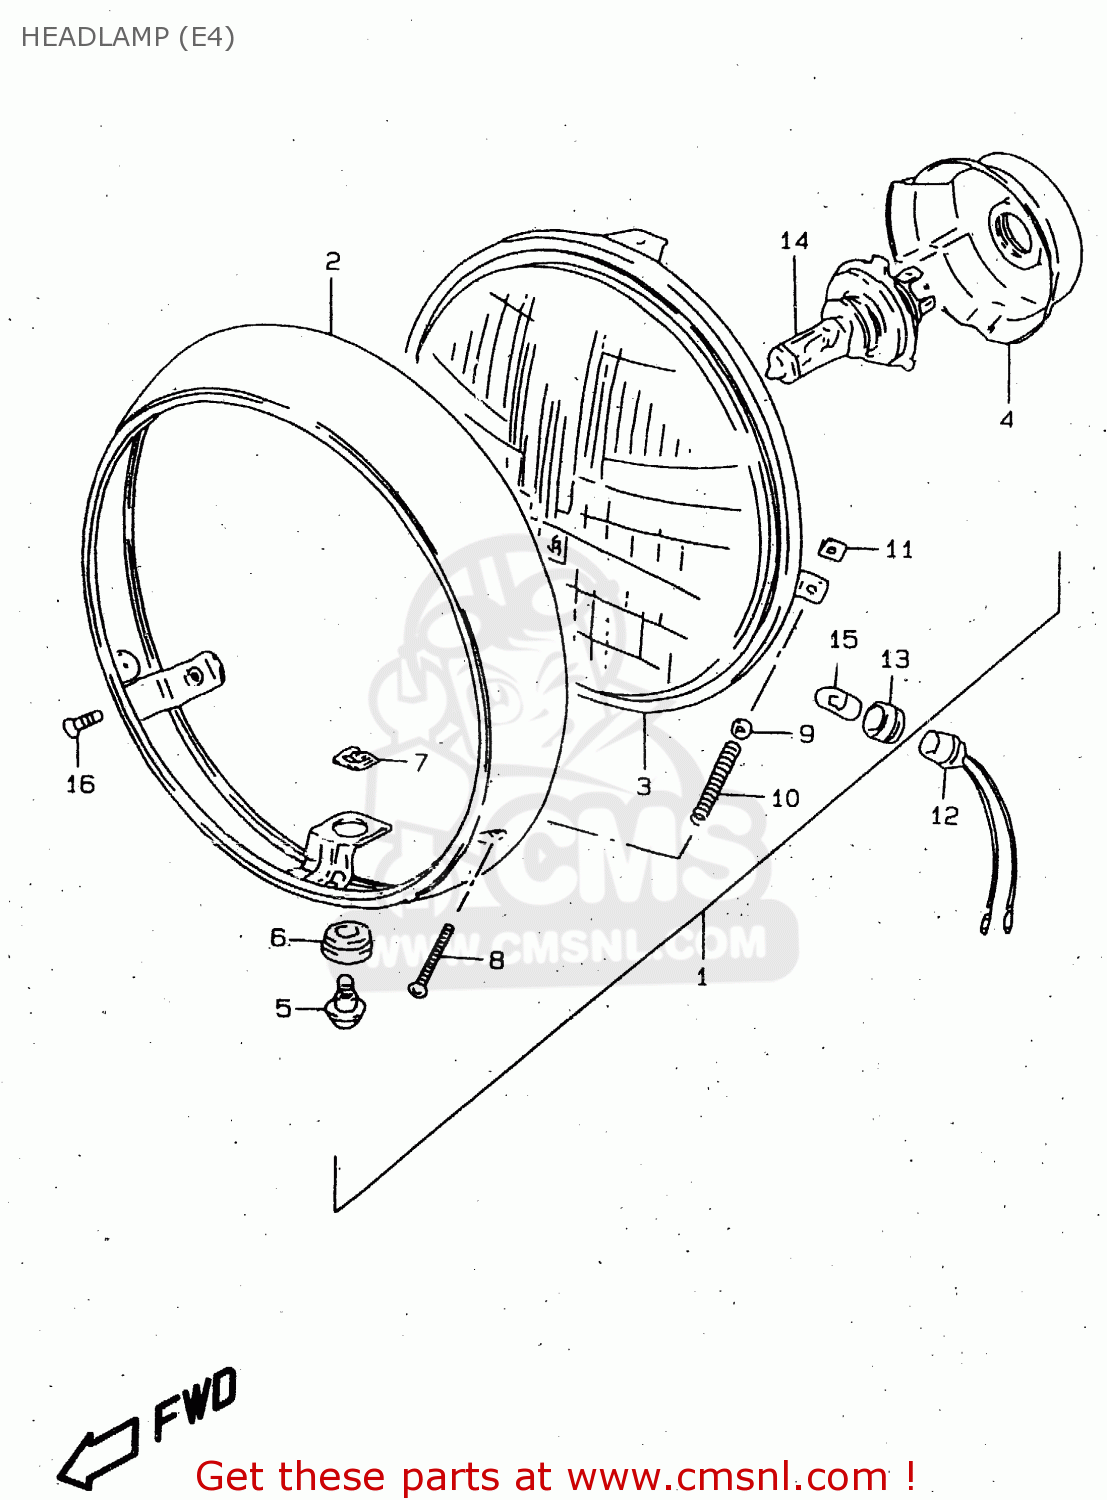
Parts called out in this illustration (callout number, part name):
1	HEADLAMP ASSY
2	RIM
3	LAMP UNIT
4	COVER,SOCKET
5	SCREW,MOUNTING
6	CUSHION
7	NUT
8	SCREW
9	WASHER
10	SPRING
11	NUT
12	SOCKET
13	JOINT,RUBBER
14	BULB(12V60/55W,H4)
15	BULB(12V4W)
16	SCREW
